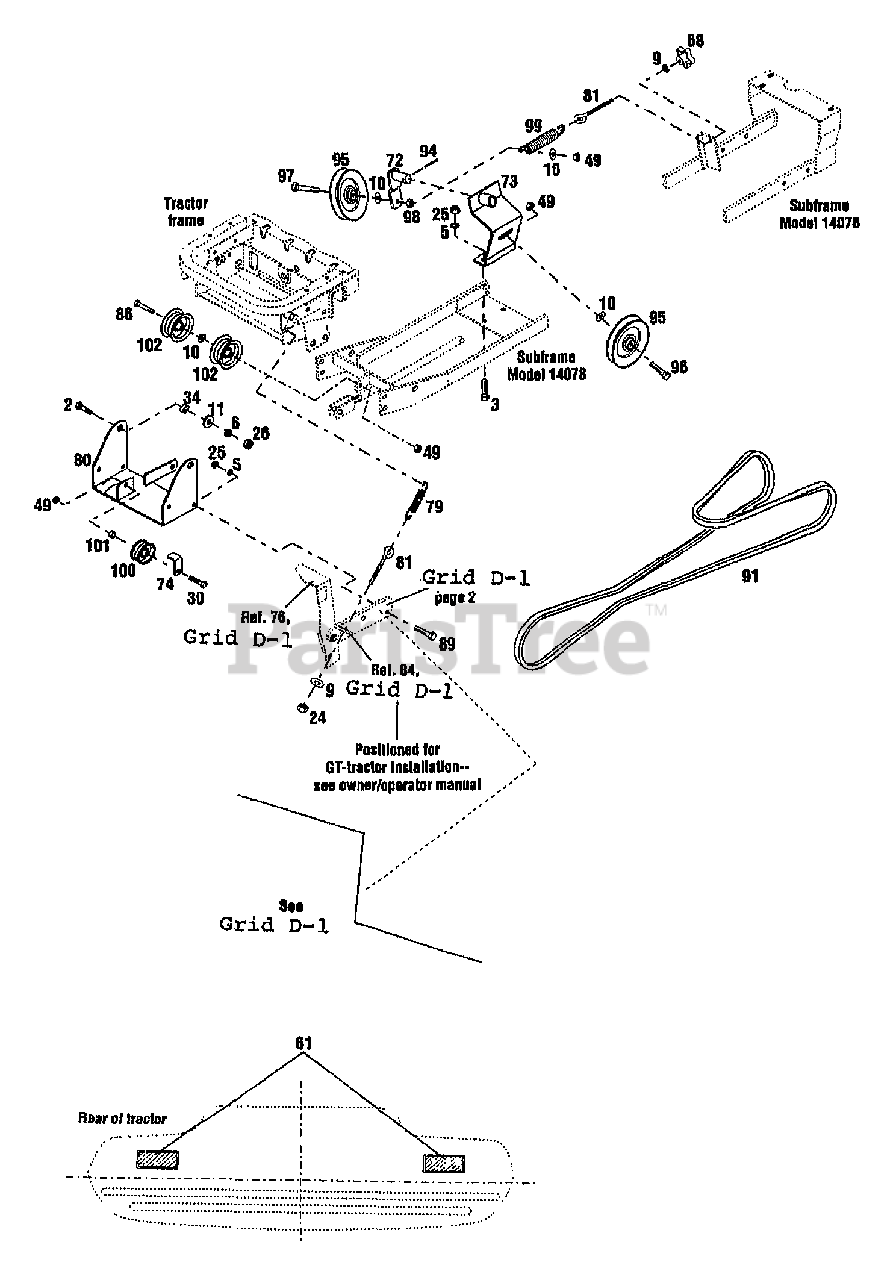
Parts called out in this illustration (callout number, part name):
2	SCR-HH 1/2-13X1.5 G5 ZP
3	SCR-HH 3/8-16X.75 G5 ZP
5	WASHER-LK .375 @ DEPL
6	WASHER-LK .5
9	WASHER-FLAT 5/16 SAE
10	WASHER-FLAT 3/8 SAE
11	WASHER-1.06X.531X.1 ZP
24	NUT-HEX 5/16-18 ZP
25	NUT-HEX 3/8-16 ZP
26	NUT-HEX JAM 1/2-13
34	SPACER-TUBULAR
49	NUT-LOCK 3/8-16
61	REFLECTOR
72	BRACKET-IDLER ARM
73	ASSM-PLATE IDLER
74	GUIDE-BELT
79	SPRING-EXTENSION
80	BRKT-PIVOT
81	BOLT-EYE
86	SCR-HHC 3/8-16X3.25
89	SCR-HH 3/8-16X1.25
91	BELT-V
94	PIN-COTTER
96	SCR-HH 3/8-16X1.75 G5 ZP
97	SCR-HH 3/8-16X2.25 G5 ZP
98	NUT-HEX/JAM 3/8-16
99	SPRING
100	PULLEY-IDLER
101	SPACER
102	PULLEY-IDLER 2" DIA
